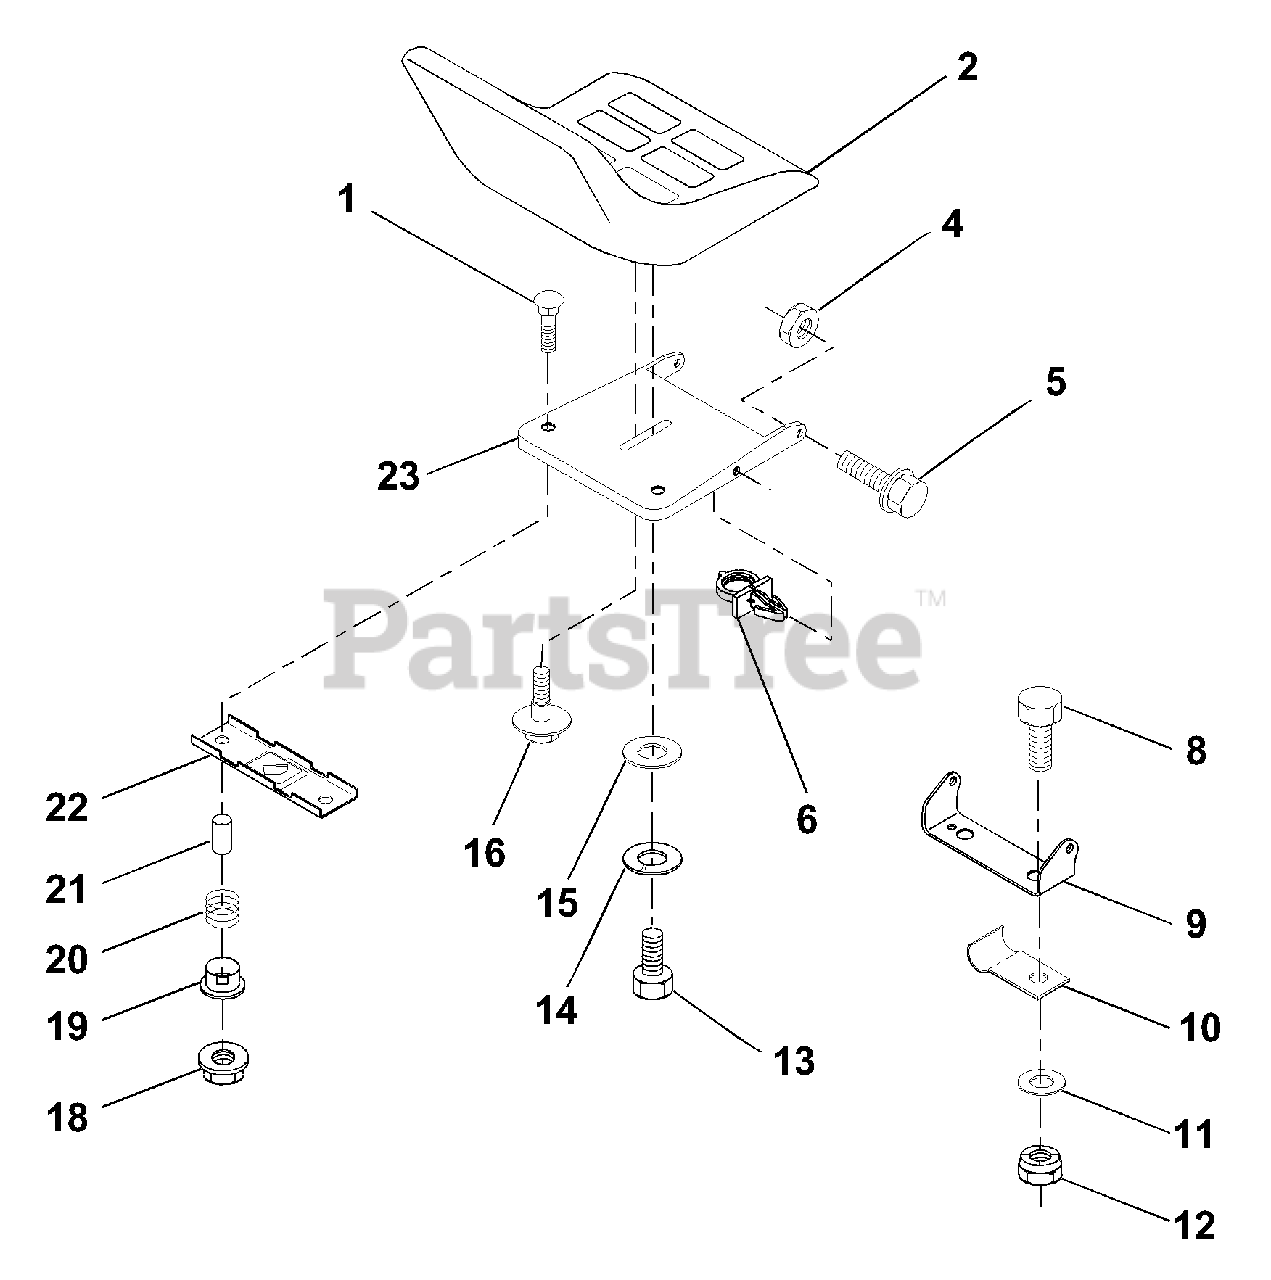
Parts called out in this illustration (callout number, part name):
1	Bolt, Carriage 1/4-20 x 1-3/8
2	Seat
4	Locknut, Hex w/Ins 5/16-18
5	Bolt, Shoulder 5/16-18 UNC
6	Clip, Push-In
8	Bolt, Fin Hex 3/8-16 UNC x 1
9	Bracket, Pivot Seat
10	Clip, Insulated
11	Washer 12/32 x 2 x 10 Ga.
12	Nut, Lock Hex w/Wsh 3/8-16
13	Bolt Hex 1/2-13 x 7/8
14	Washer Lock Hvy. Hlicl Spring 1/2
15	Washer, 17/32 x 1-3/16 x 12 Ga.
16	Bolt, Shoulder
18	Nut, Hex Large Flange Lock
19	Bushing, Snap
20	Spring, Compression
21	Spacer, Split 28 Id. x .88 Lg.
22	Bracket, Switch, Mounting
23	Pan, Seat
